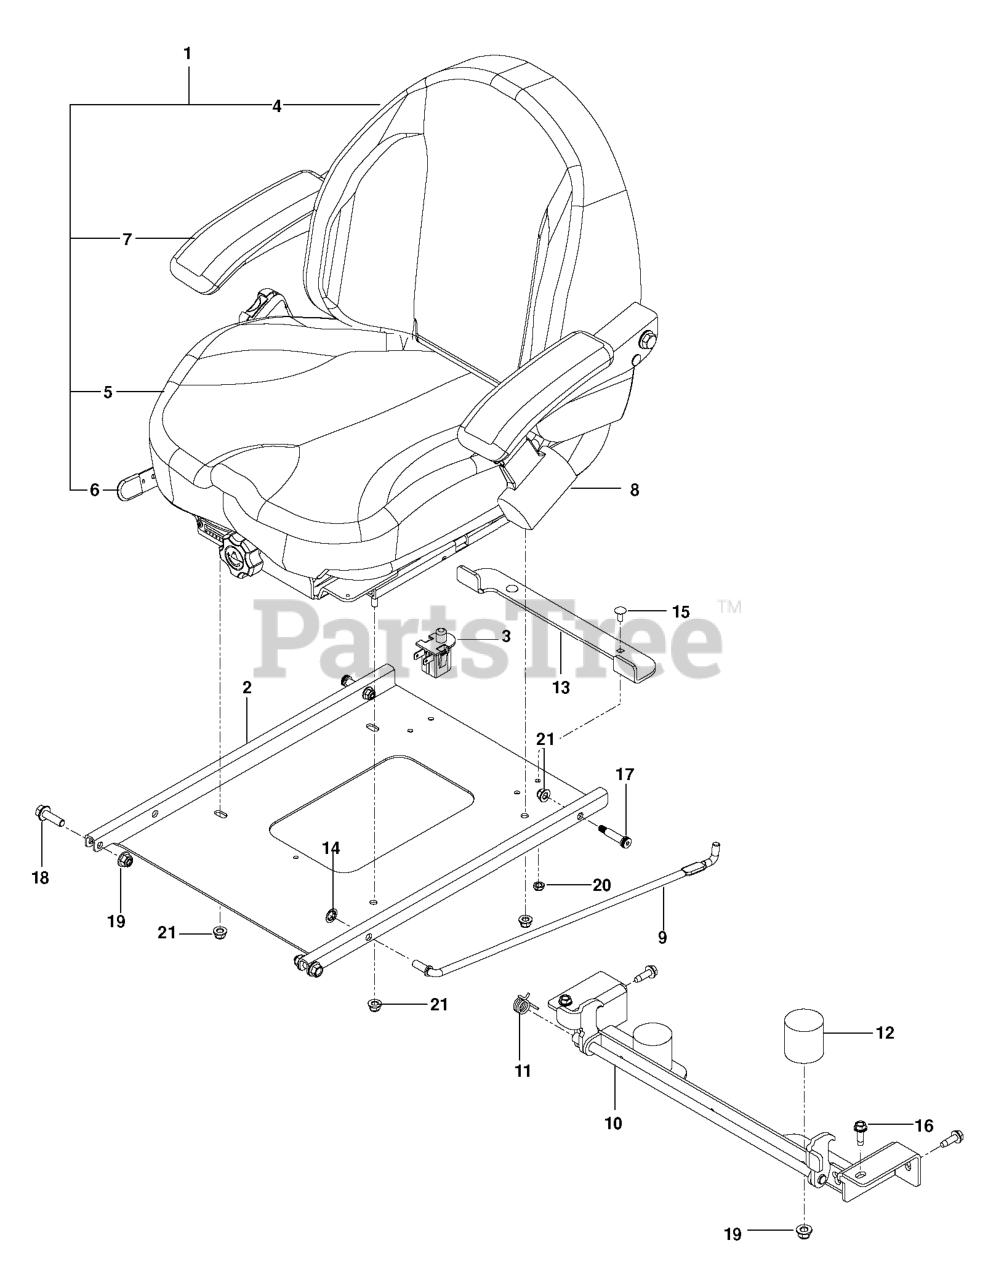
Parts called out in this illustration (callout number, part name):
1	Seat Assy
2	PAN, SEAT, BLACK
3	SEAT SWITCH
4	COVER, BACK
5	COVER KIT, CUSHION
6	TRACK KIT
7	ARMREST, LT
8	SEAT BELT, RETRACTABLE
10	LATCH.SEAT.BLACK
11	SPRING, TORSION
12	BUMPER, RUBBER
13	STOP, SEAT, BLK
14	NUT 3/8 PALNUT RTNG BLK PHOS
15	RHSSNB, 1/4-20X5/8
16	RP BLT 5/16-18 X 1 THRD FORM D
17	BOLT, SHOULDER 3/8 X 1.25
18	HHFS 3/8-16 X 1.25 GD 5
19	NUT 3/8-16 HEX FLG NYLOC ZD
20	JAM NUT 1/4C (2 2 PW01)
21	5/16-18 NYLOC FLANGE NUT
